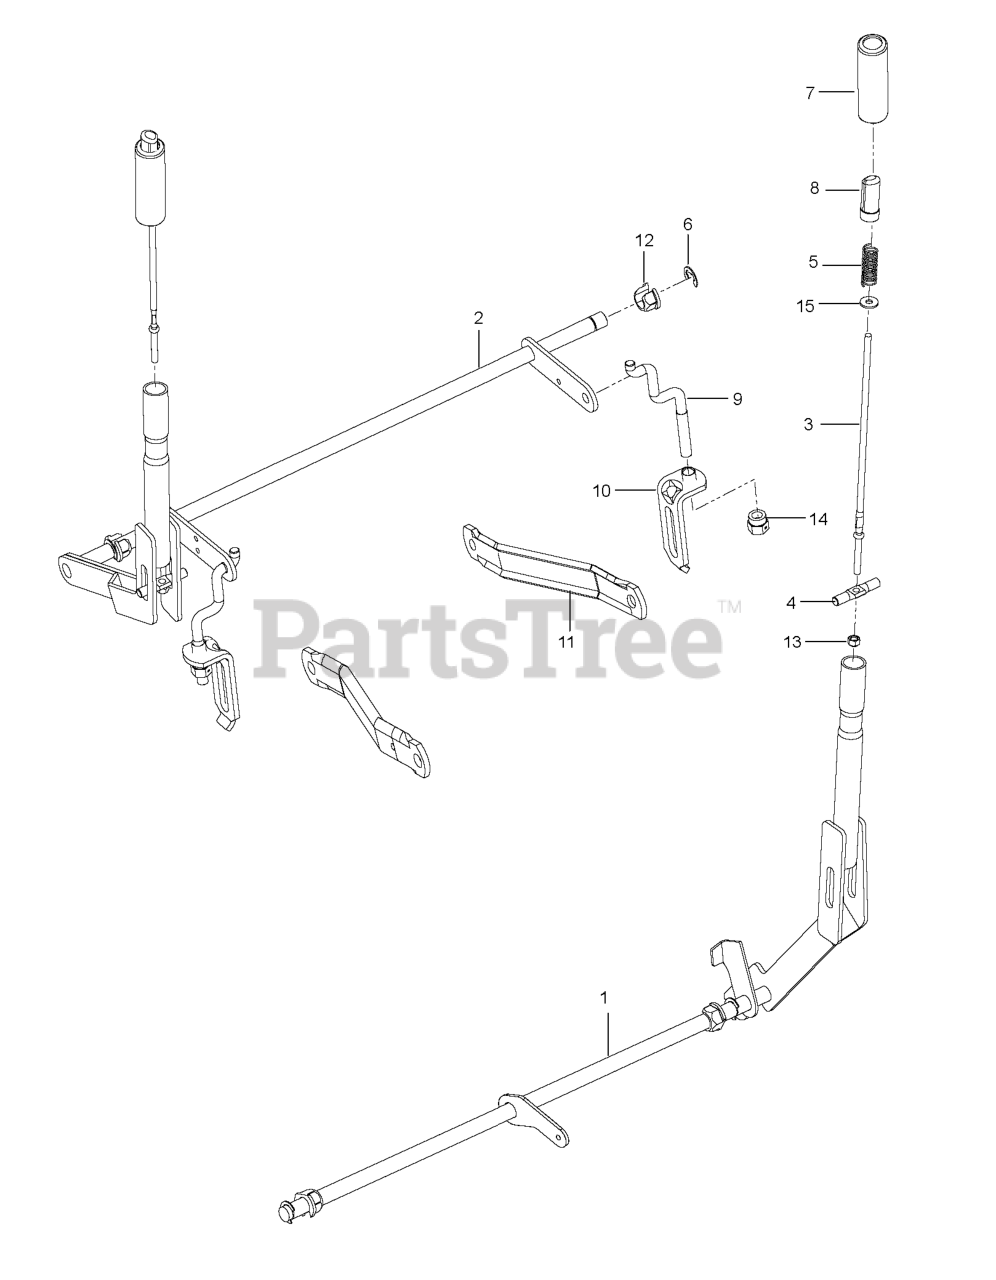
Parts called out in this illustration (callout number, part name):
1	SUBASM.SHAFT.BRAKE.WLDMNT.MED
2	DECK.LIFT.PNT.WELDMENT.RZ.BLK
3	ROD, HANDLE RELEASE
4	RB ROD, LATCH RELEASE
5	SPRING, COMPRESSION
6	RETAINING RING LT
7	GRIP, HANDLE, BLACK 4"
8	BUTTON, PUSH, BLACK
9	LINK, REAR SUSPENSION
10	ASSEMBLY, BRKT LINK
11	ARM.SUSPENSION.MOWER
12	PLASTIC NUT
13	LOCKNUT.NYLOC.1/4-20
14	NUT, LIFT LINK 7/16-20
